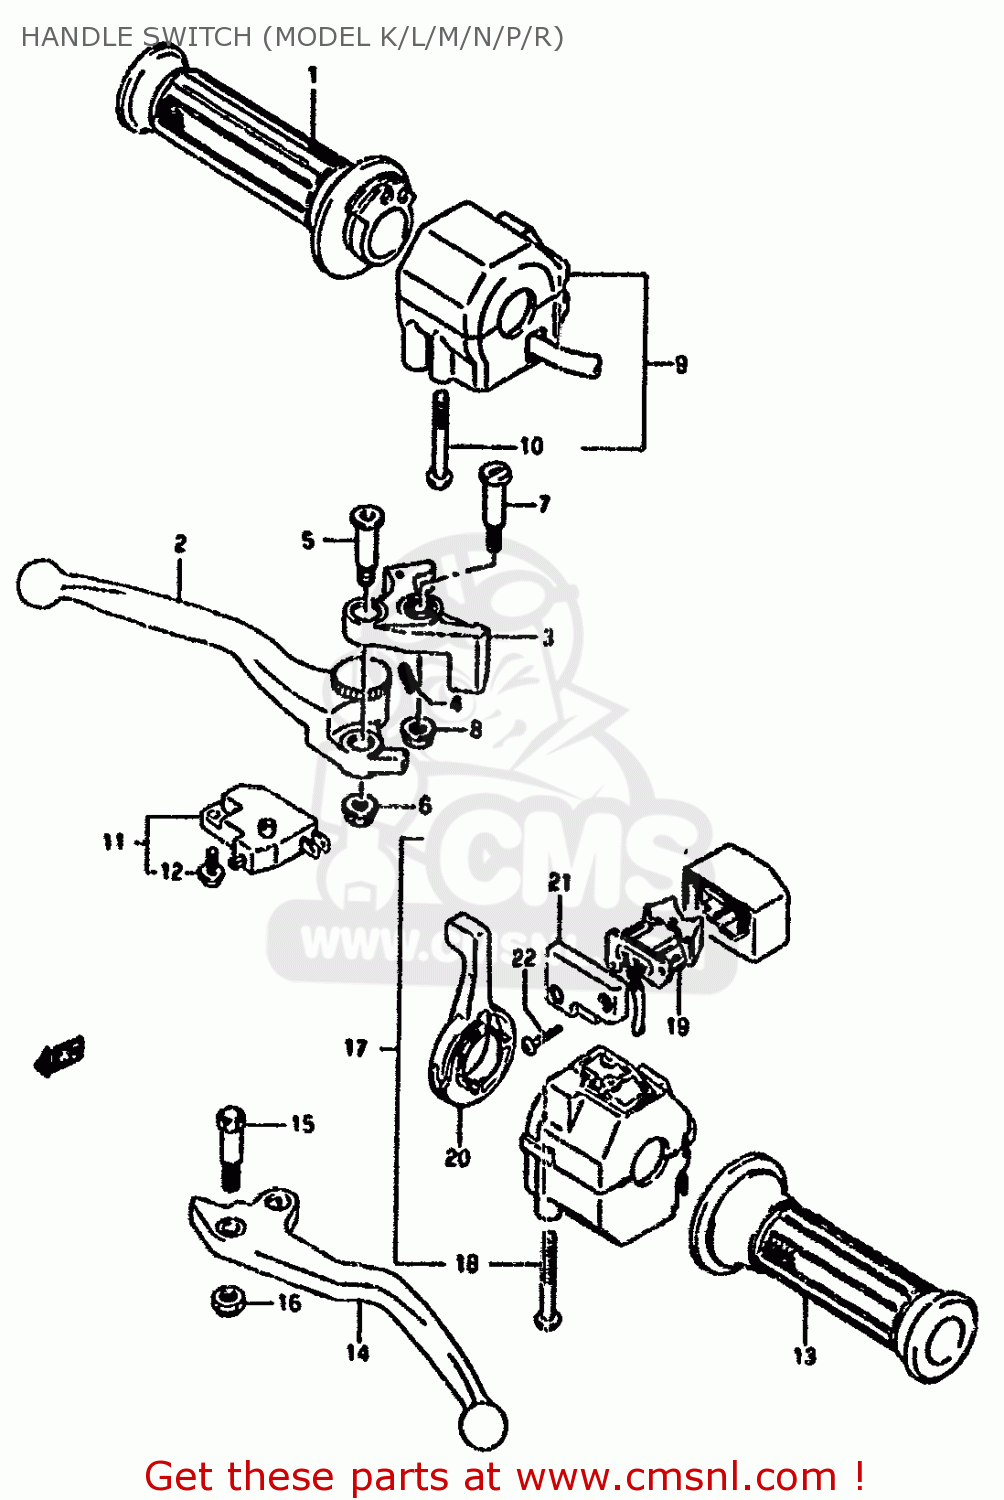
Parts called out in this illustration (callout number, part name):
1	GRIP,THROTTLE
2	LEVER,ADJUST
3	KNOCKER
4	SPRING
5	BOLT,LEVER
6	NUT
7	BOLT,LEVER PIVOT
8	NUT 6MM
9	SWITCH ASSY,HANDLE RH
10	SCREW, 5X45
11	SWITCH ASSEMBLY,STOP
12	SCREW
13	GRIP,L
14	LEVER,CLUTCH
15	BOLT,LEVER
16	NUT
17	SWITCH ASSY,HANDLE LH
18	SCREW, 5X45
19	SWITCH,SCREEN
20	LVER,CHOKE
21	COVER,SCREEN SWITCH
22	SCREW,SCREEN SWITCH
